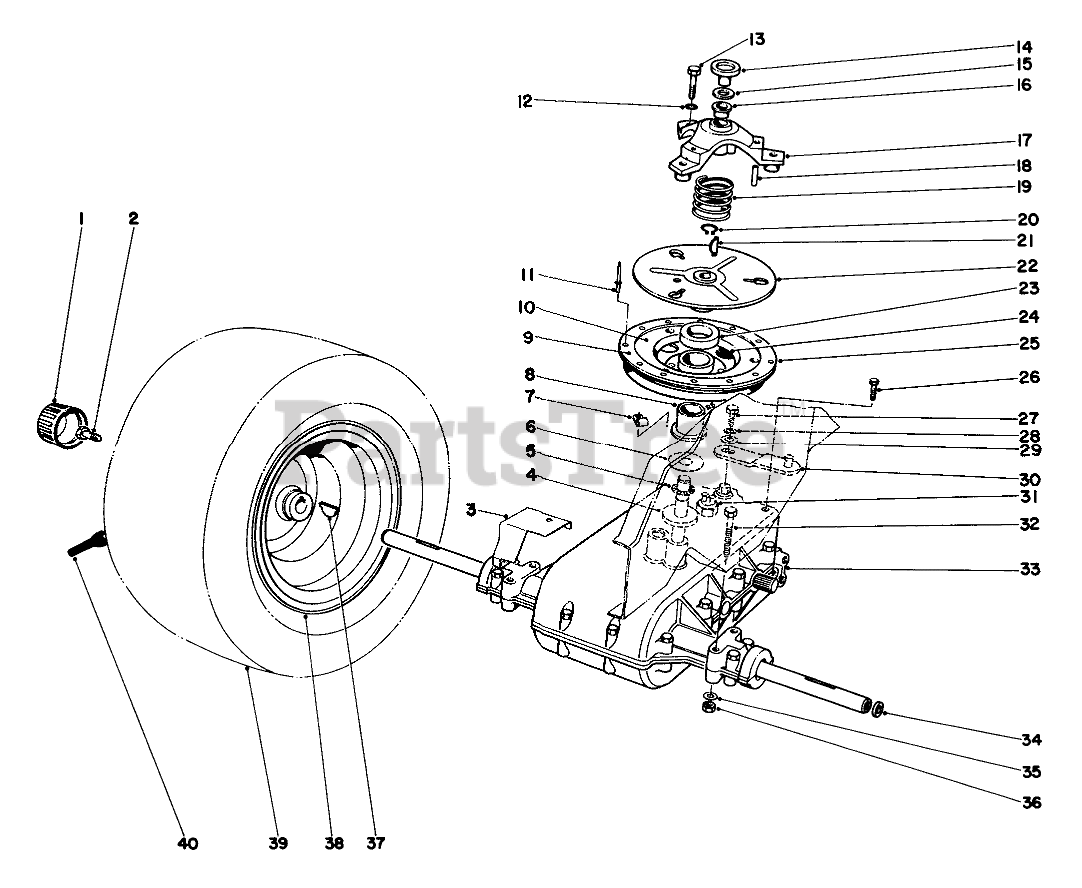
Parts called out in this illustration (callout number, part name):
1	Cap-Hub
2	CAPSCREW 3/8 16 3/4
3	GRASS SHIELD B
4	SPACER
5	NEEDLE BRG
6	THRUST WASHER
7	CLIP-FUEL LINE
9	CLUTCH PAD
10	RETAINER RING R
11	RIVET-POP
12	WASHER-LOCK
13	SCREW-HH
14	CLUTCH CAP
15	THRUST RACE
16	BUSHING-FLANGE
17	Clutch Cover (Incl. Ref. #16 & 18)
18	NEEDLE BRG
19	COMPRESSION SPRING
20	RING-SNAP, EXTERNAL
21	KEY-WOODRUFF
22	Clutch Plate
23	WASHER FELT
25	Sheave Assembly (Incl. Ref. #8-11)
26	SCREW-HWHTF
27	SCREW-HH
28	WASHER-LOCK
29	WASHER-FLAT
30	SHIFT LEVER WA B
31	NEUTRAL SWITCH
32	SCREW-HH
33	Transaxle
34	SPACER-WHEEL
35	WASHER-PLAIN
36	NUT-LOCK, CONE
37	Hi Pro Key
38	WHEEL ASM
40	STEM-VALVE
